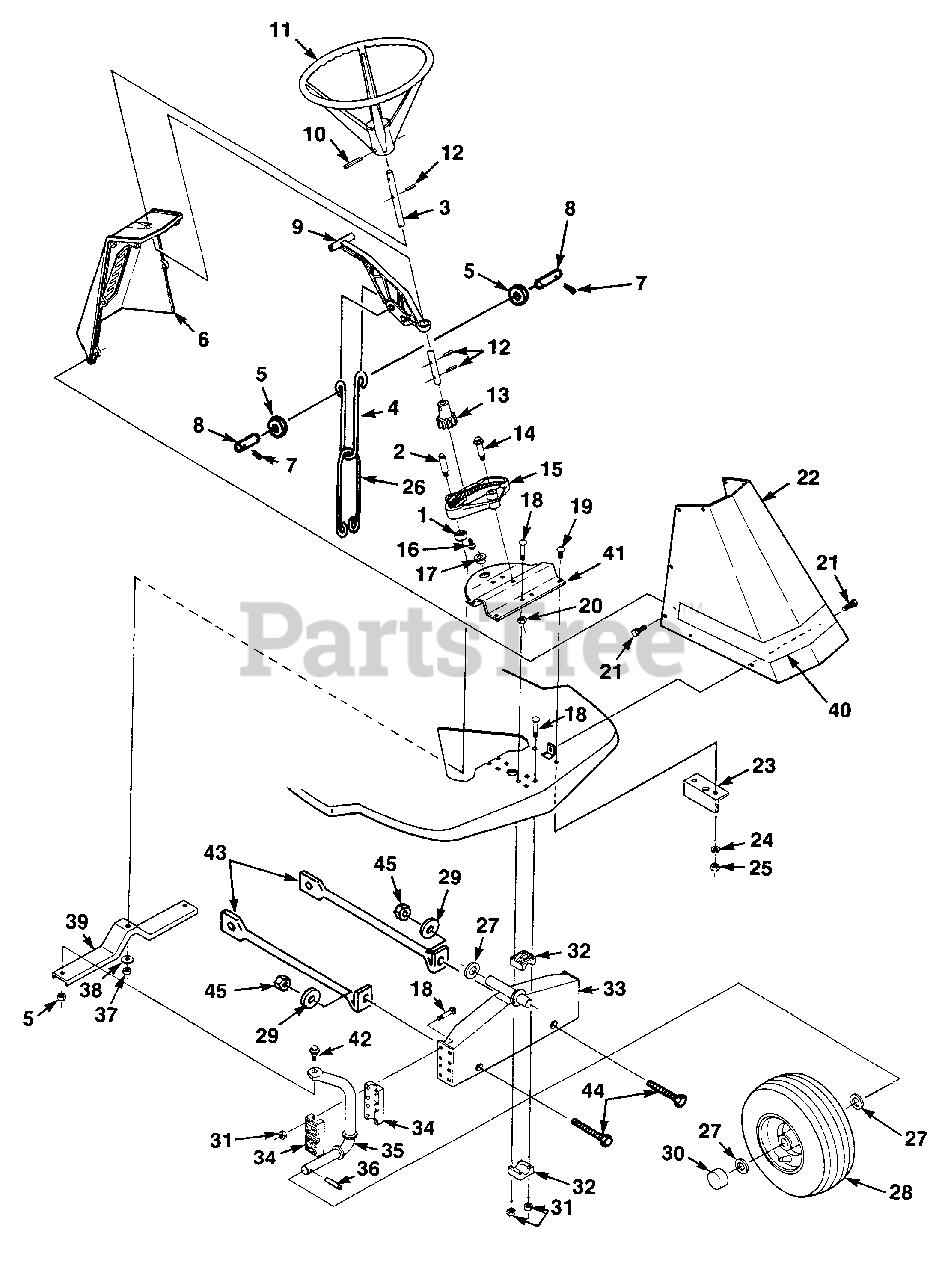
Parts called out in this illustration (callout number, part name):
1	BUSHING- Ball
2	STUD- Steer
4	LINK- Lift
5	WASHER- 1/2"
6	PANEL- Console
7	PIN- Cotter
8	PIN- Retainer
9	HANDLE- Lift
11	WHEEL- Steering
13	PINION- Steering
14	BOLT- Shoulder 3/8-16 x 2.125
15	SECTION- Steering
16	SCREW- 1/4-20 x 1/2
18	BOLT (1/4-20 x 1 3/4 Carr.)
19	BOLT (1/4-20 x 3/4 Carr. Sq. Nk.)
20	NUT- 3/8-16 C'Lock
21	BOLT (1/4-14 x.44 Swedge form)
22	SUPPORT- Steering
24	WASHER- Lock 1/4
25	NUT- 1/4-20 hex
26	LINK- Lower lift
27	WASHER- (FLat 3/16)
28	WHEEL & TIRE
29	WASHER- Plain (Flat 13/32)
31	NUT (1/4-20 hex c'lock)
33	AXLE- Front
35	SPINDLE- LH Wheel
36	PIN
37	NUT- C'Locking-hex 3/8-24
38	WASHER- Flat 3/8
39	BRACKET- Steering
40	DECAL- Product identification
41	BRACKET- Reinforcement
43	SUPPORT- Frame axle
44	BOLT (3/8-16 x 5/8)
45	NUT (3/8-16 c'lock)
